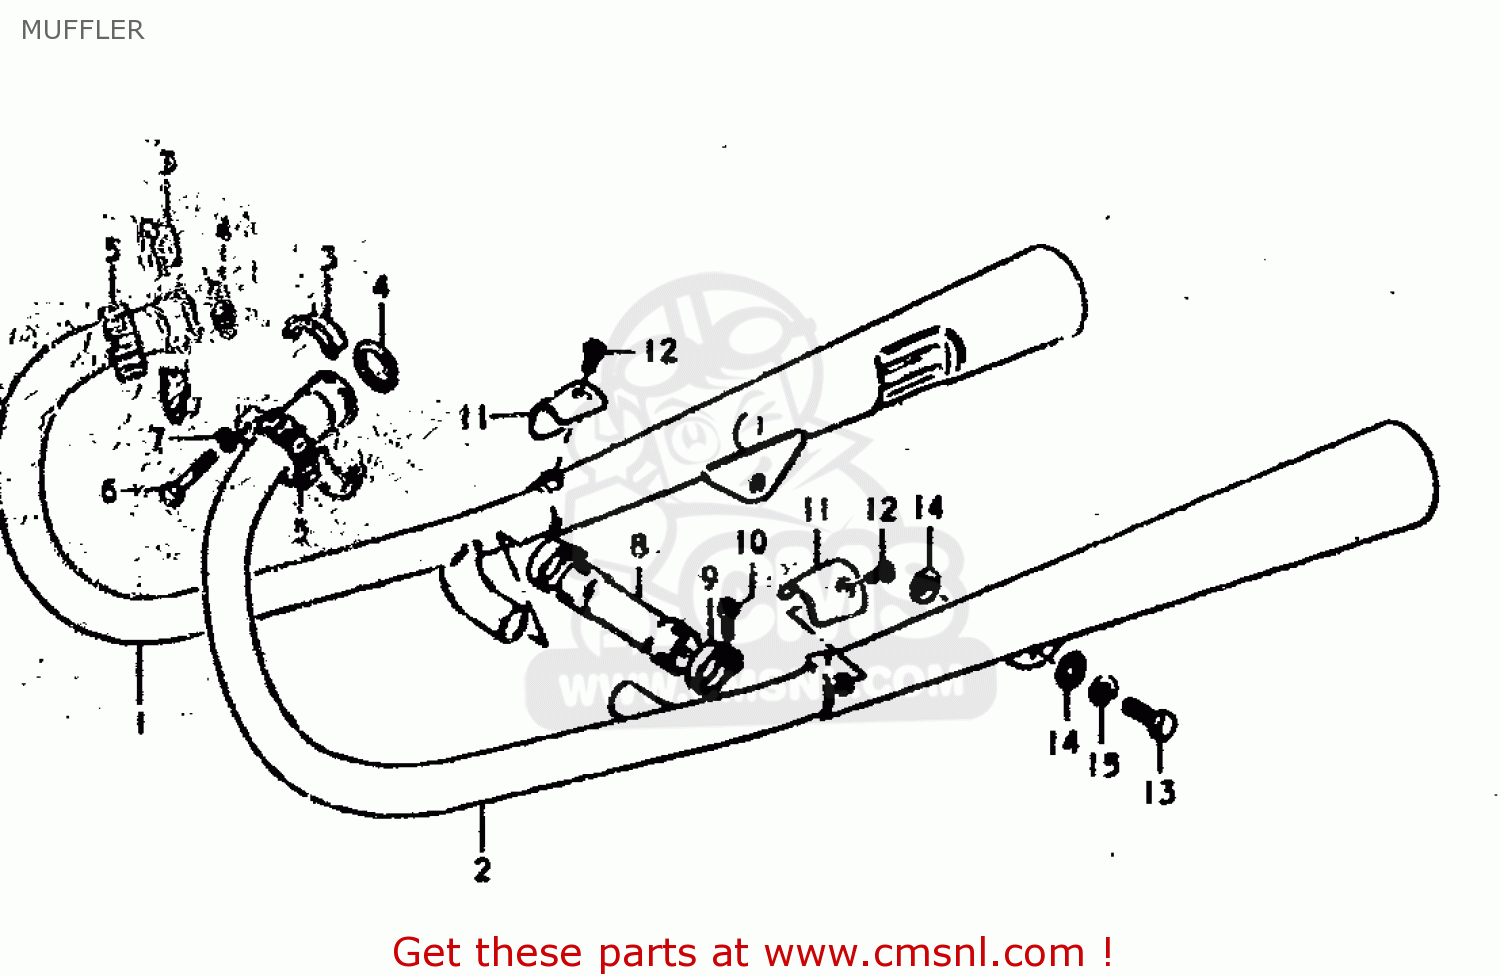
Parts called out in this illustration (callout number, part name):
1	BODY,MUFFLER
2	BODY,MUFFLER
3	PLATE,EXHAUST P
4	GASKET,EXHAUST PIPE (NAS)
5	CLAMP,EXHAUST PIPE
6	BOLT
7	LOCK WASHER
8	PIPE,EXHAUST COUPLER
9	CLAMP
10	BOLT
11	COVER,MUFFLER,RIGHT
12	SCREW
13	BOLT 10X25
14	WASHER
15	LOCK WASHER
